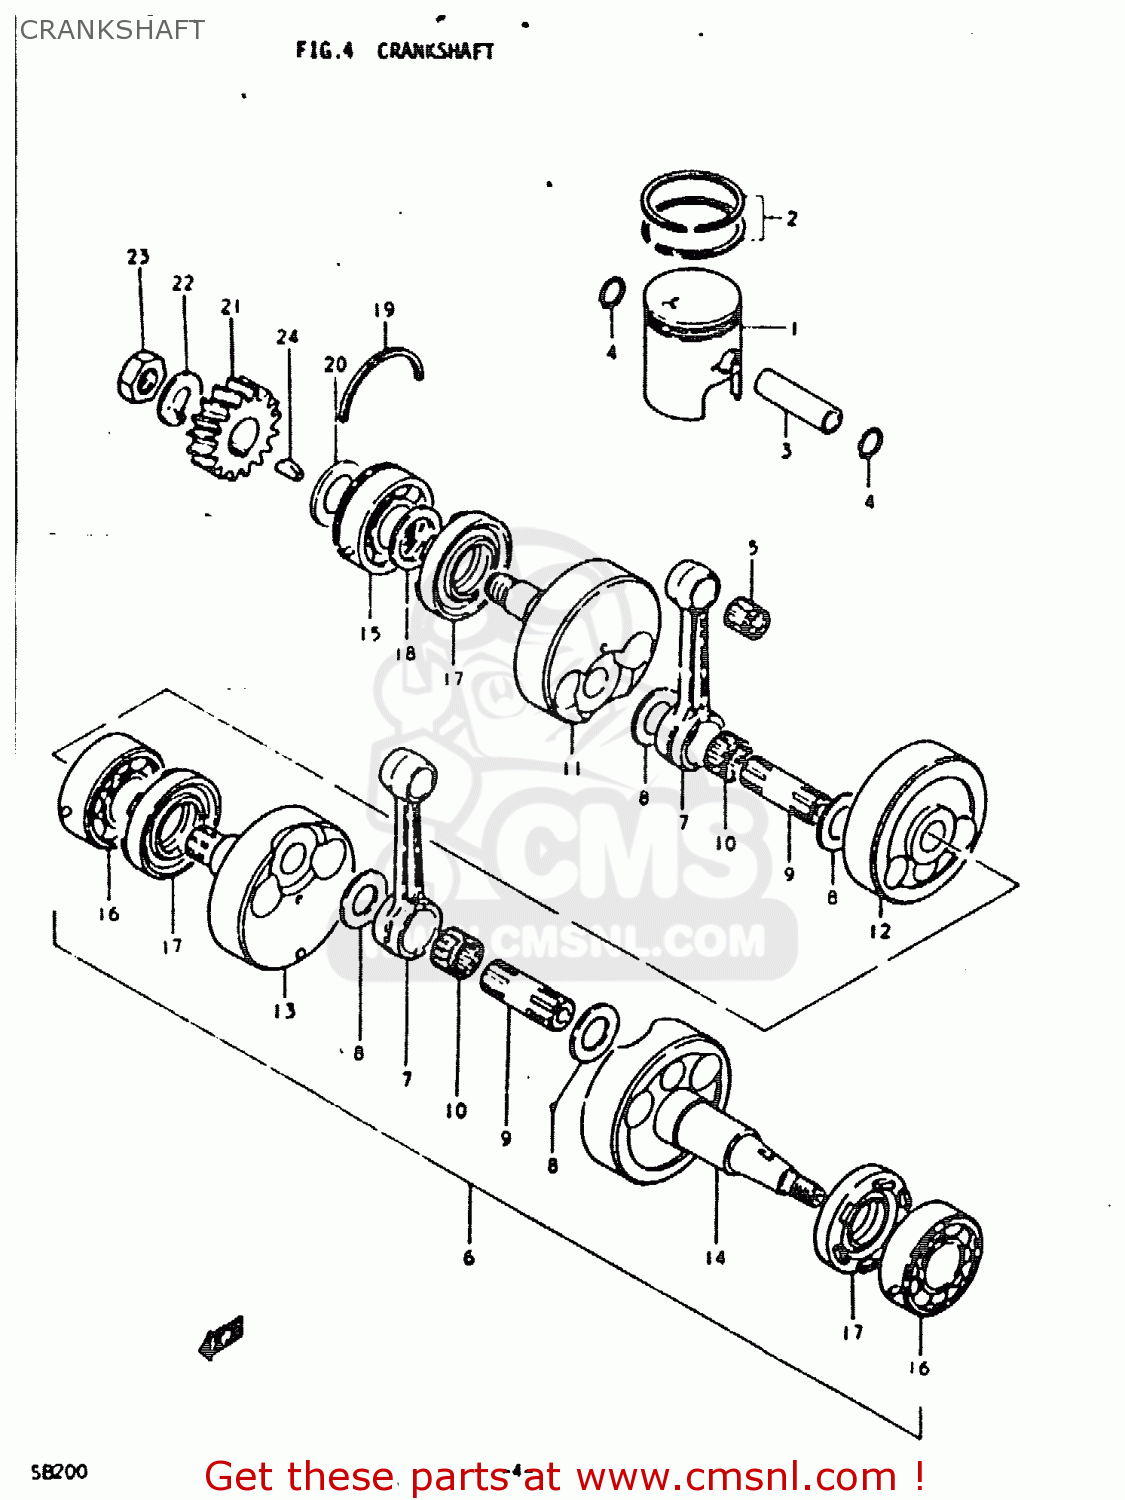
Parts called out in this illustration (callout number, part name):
1	PISTON
2	RING SET,PISTON
3	PIN,PISTON 14MM
4	RING,SNAP 14MM
5	BEARING
6	CRANKSHAFT ASSY
7	ROD, CONNECTING
8	WASHER(19X32X1)
9	PIN,CRANK
10	BEARING(19X25X16)
11	CRANKSHAFT, RH
12	WEB, CRANK
13	CRANKSHAFT, MIDDLE
14	CRANKSHAFT, LH
15	BEARING(25X62X17)
16	BEARING
17	SEAL,OIL(30X62X11)
18	WASHER
19	C RING
20	WASHER(20X48X1)
21	GEAR, PRIMARY DRIVE
22	WASHER
23	NUT
24	KEY
